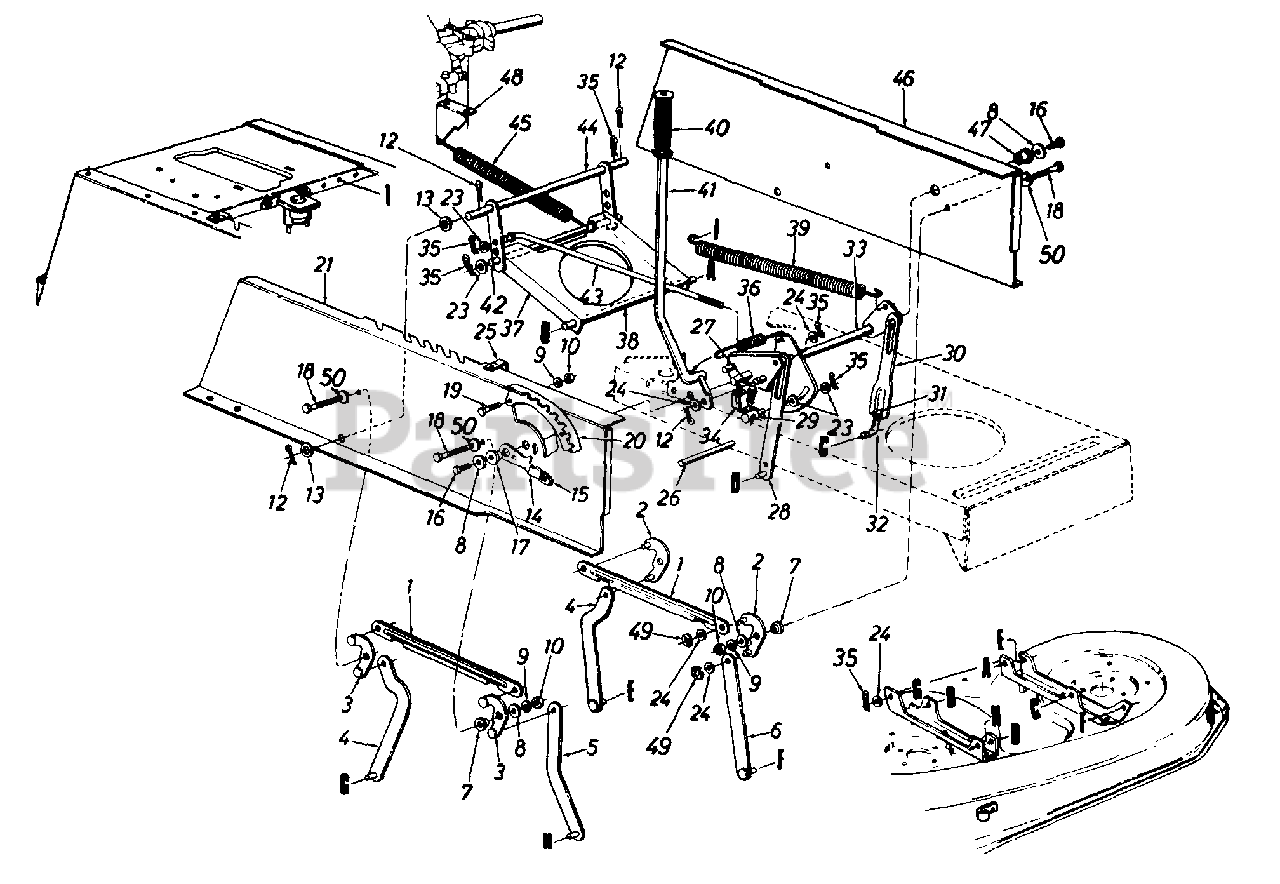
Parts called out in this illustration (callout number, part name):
3	Pivot Link Ass'y. - R.H.
7	Shld. Spacer .318" I.D.
8	Fl-Wash. .344" I.D. x .62" O.D.
9	L-Wash. 5/16" I.D.
10	Hex Nut 5/16-18 Thd. (Gr. 5)
12	Cotter Pin 1/8" Dia.
13	Fl-Wash. .635" I.D. x 1.0" O.D.
14	Height Adj. Stop Lever Ass'y.
15	Knob
16	Hex Wash. TT-Tap Scr. 5/16-18 x .75" Lg.
17	Flange Brg. .63" I.D.
18	Hex Wash. Hd. Scr. 5/16-18 x .875" Lg.
19	Hex Bolt 5/16-18 x .75" Lg.
20	Index Brkt.
24	Fl-Wash. .531" I.D. x .93" O.D.
25	Clamp
26	Running Board Rod
27	Hex Wash Hd Tap Scr
31	Hex Nut 1/2-20 Thd. (Gr. 5)
32	Lift Link Adjuster
35	Inter. Cotter Pin 3/8" Dia.
36	Extension Spring
39	Extension Spring
40	Grip (Lift Handle)
43	Disengagement Rod
49	"E"-Ring
50	Bell-Wash .325" I.D.
